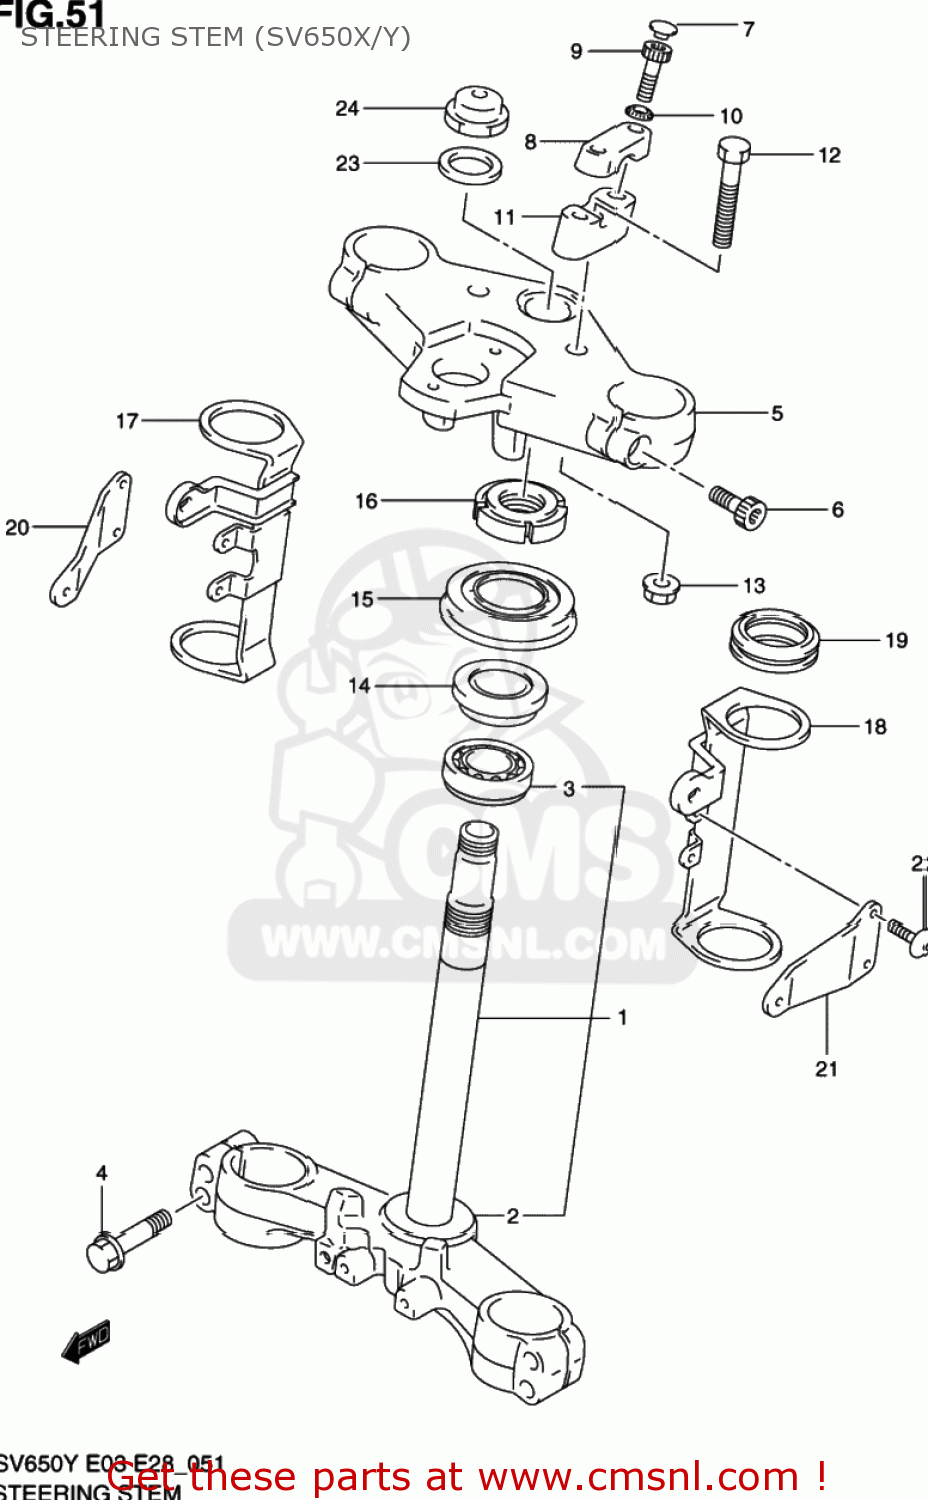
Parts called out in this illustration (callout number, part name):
1	STEM,STEERING
2	SEAL,STEERING LWR
3	BEARING(30X55X17)
4	BOLT
5	HEAD,STEERING STEM
6	BOLT(8X32)
7	CAP(OD:11)
8	HOLDER,HANDLE UPR
9	BOLT
10	WASHER
11	HOLDER,HANDLE LWR
12	BOLT,LWR HOLDER(10X45)
13	NUT
14	BEARING(25X47X15)
15	SEAL,OIL(34X69X11.9)
16	NUT,STEERING STEM(25X44X10)
17	BRACKET COMP,HEADLAMP
18	BRACKET COMP,HEADLAMP
19	DAMPER,HEADLAMP HSG BRACKET
20	STAY,HEADLAMP HOUSING,R
21	STAY,HEADLAMP HOUSING,L
22	SCREW(6X12)
23	WASHER(22.5X35.9X1.6)
24	NUT
